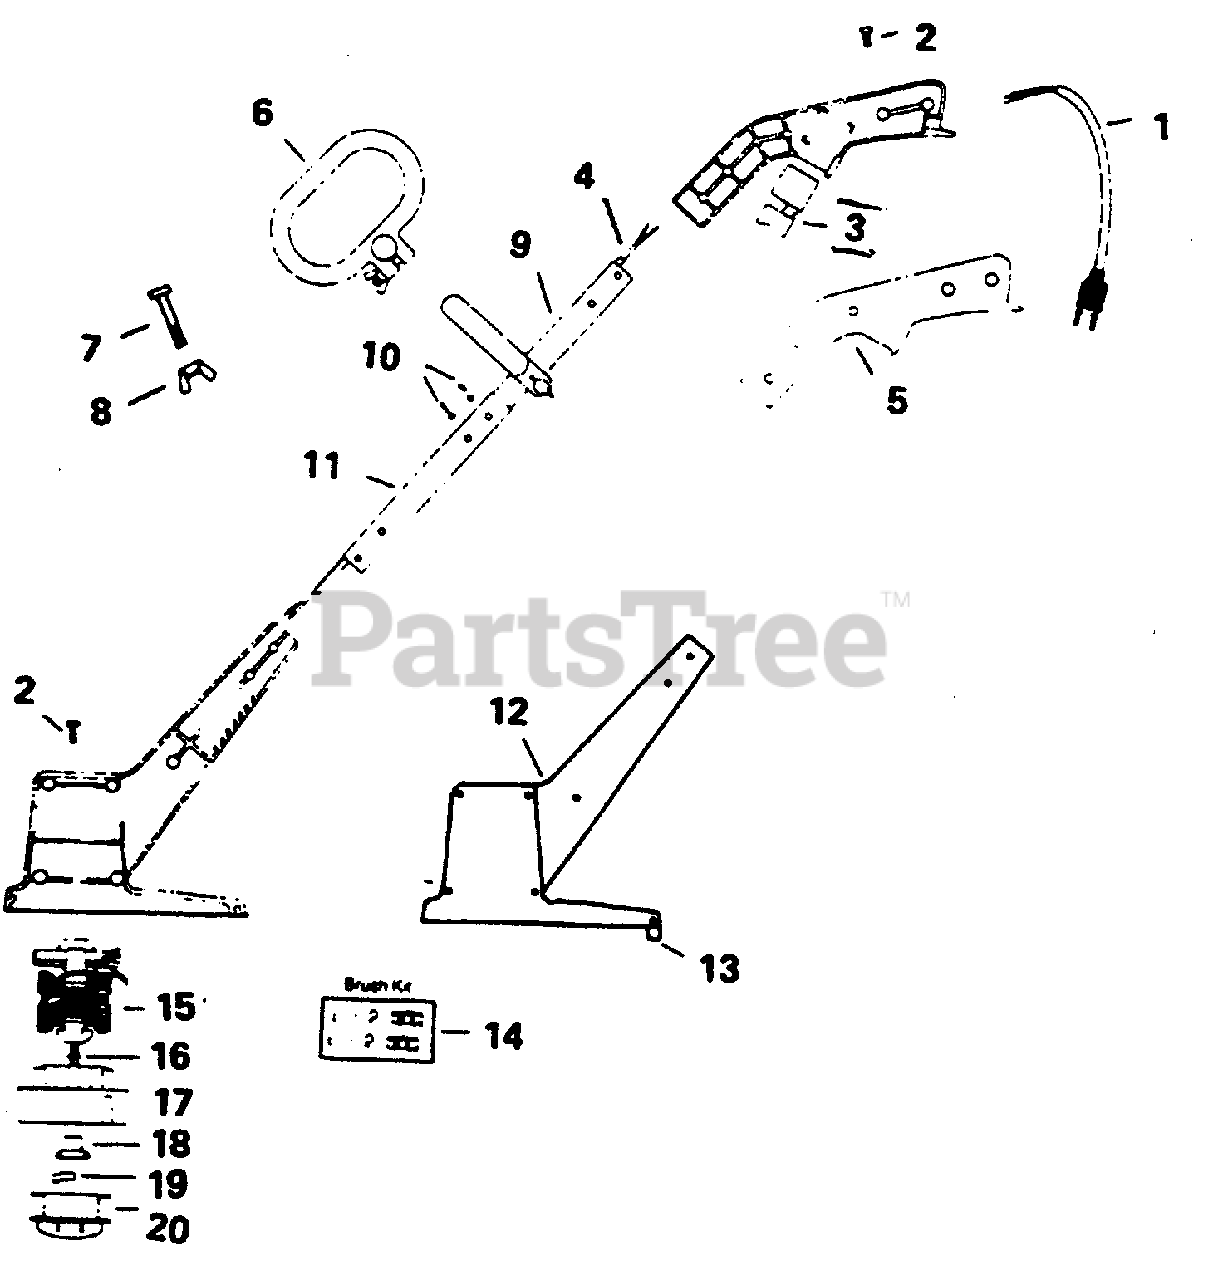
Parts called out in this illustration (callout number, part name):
1	POWER CORD PIGTAIL
5	TRIGGER HANDLE SET
6	ASSIST HANDLE
8	WING NUT
9	TUBE, UPPER
10	TUBE FASTENER KIT
11	TUBE, LOWER
12	MOTOR HOUSING SET
13	TAIL INTERFERENCE BLADE
14	BRUSH KIT
16	WASHER-THRUST
17	HUB w/LINE SAVERS
18	HUB RETAINER
19	LINE SAVERS
20	SPOOL WOUND
